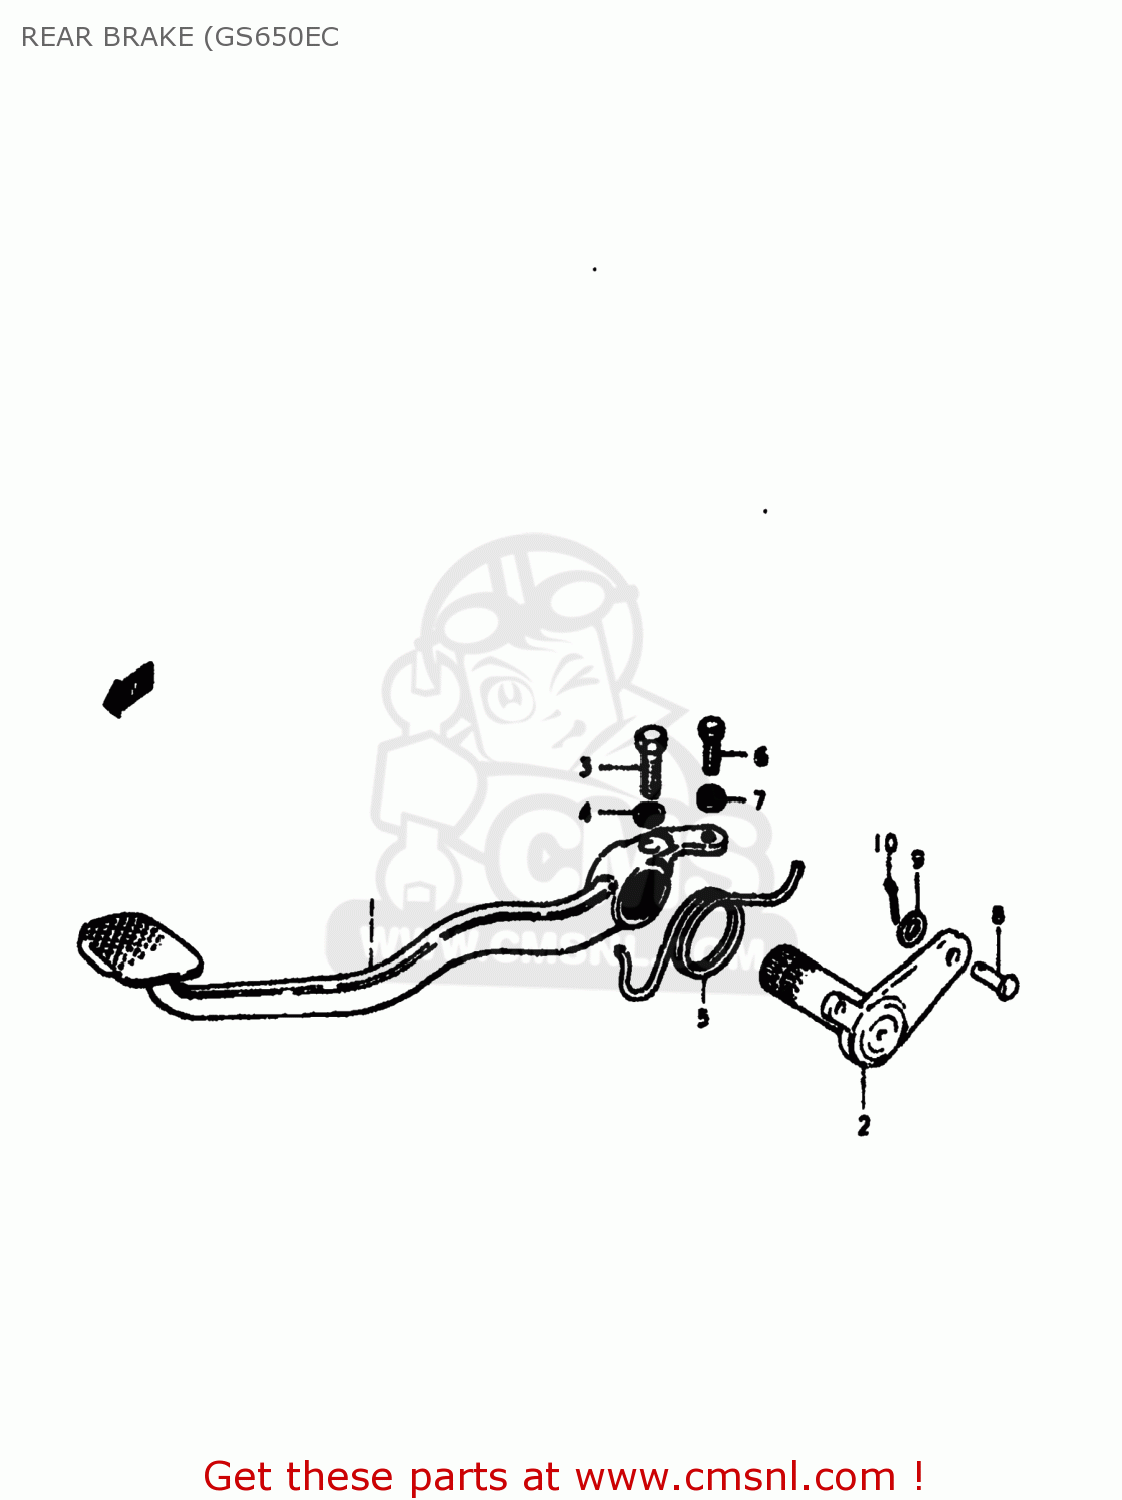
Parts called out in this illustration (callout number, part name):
1	PEDAL,BRAKE
2	ARM,BRAKE PEDAL ROD
3	BOLT
4	LOCK WASHER
5	SPRING
6	BOLT
7	NUT
8	PIN
9	WASHER
10	PIN
